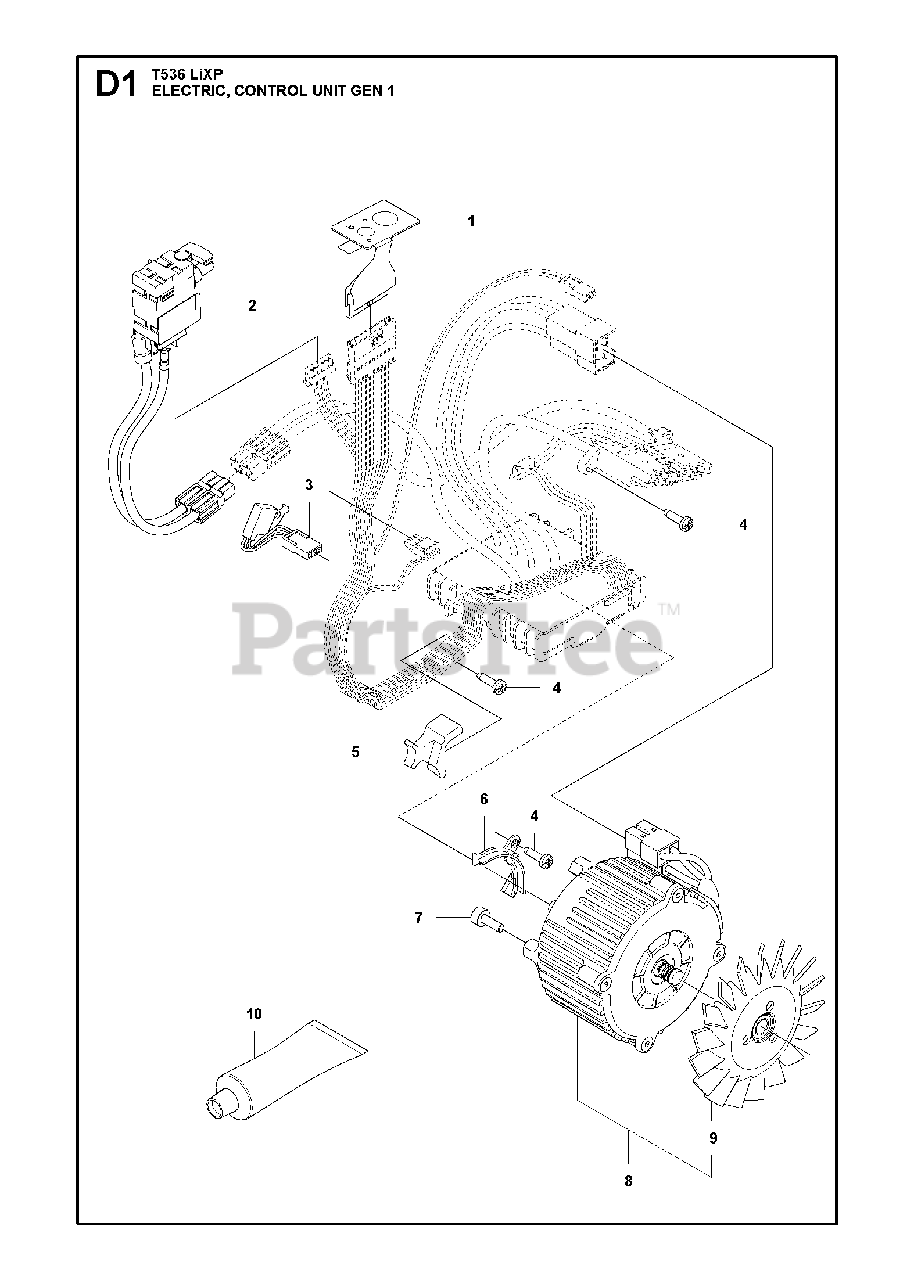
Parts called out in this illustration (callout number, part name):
1	KEYPAD
2	WIRING ASSY
3	WIRING ASSY
8	MOTOR ASSY BLDC D70
10	GREASE TUBE Q8 RUYSDAEL WR2
